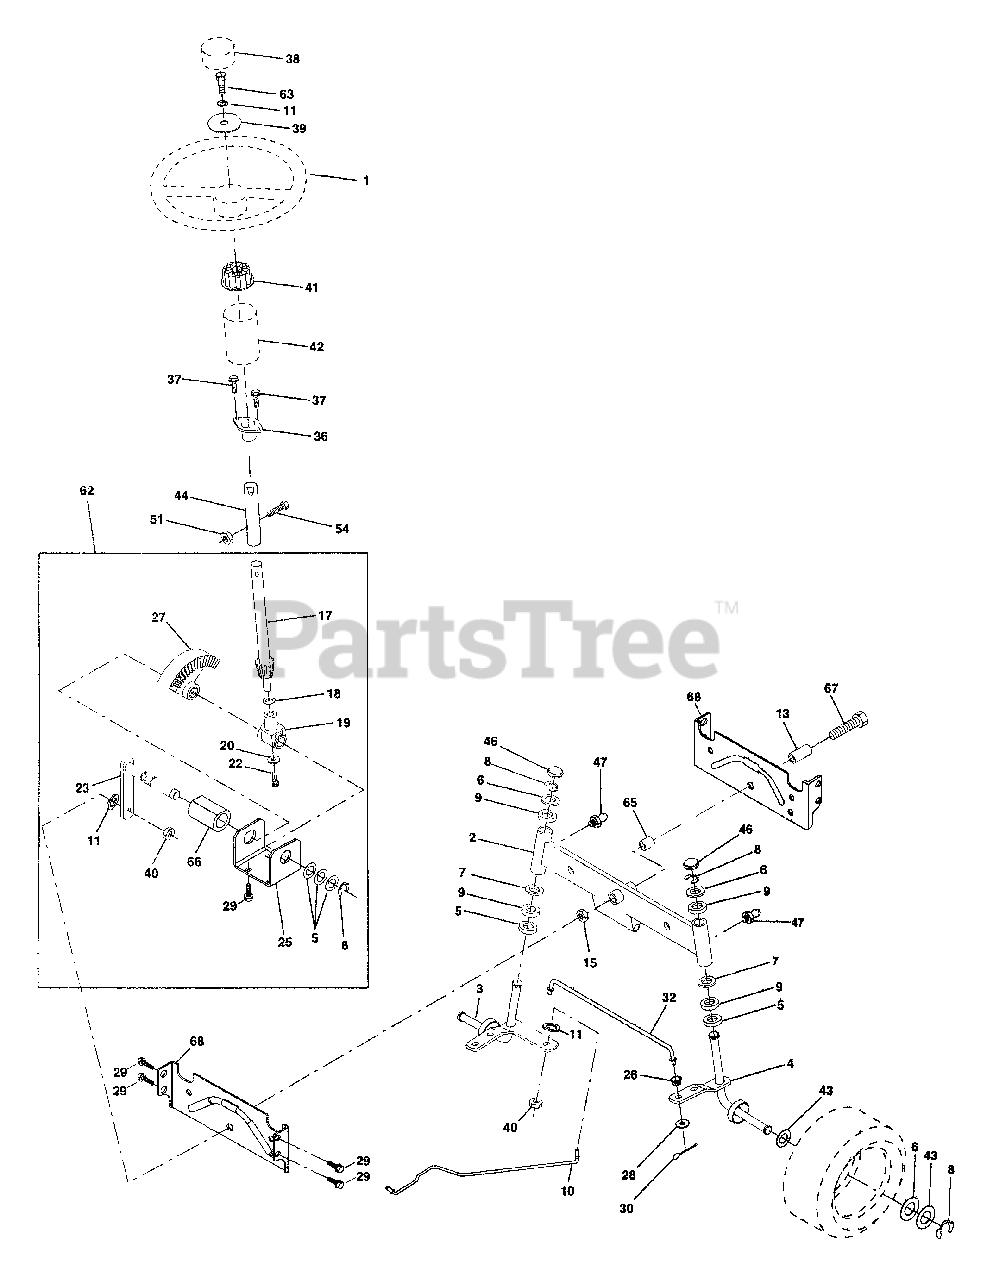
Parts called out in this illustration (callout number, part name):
1	Wheel Steering
2	Axle Asm STMP Dropped STL
3	Spindle Asm LH
4	Spindle Asm RH
5	Bearing Race Thrust Harden
6	Washer 25/32 X 1-5/8 X 16 Ga
7	Washer 27/32 X 1-1/4 X 16 Ga
8	Ring Klip #t5304-75
9	Bearing Col Strg Blk
10	Link Drag Extended Stamp
11	Washer Lock Hvy Hlcl Spr 3/8
13	Bearing Axle STLT/GT
15	Nut Lock Flange 5/8-11 Unc
17	Shaft Asm Strg
18	Washer Thrust 515x 750x 033
19	Support Shaft
20	Washer Shim 1/4 X 5/8 X 062
22	Screw Hex Socket 1/4-20 x 5/8
23	Shaft Asm Pittman
25	Bracket Steering
26	Bushing Link Drag Blk LR
27	Gear Sector
28	Washer 13/32 X 7/8 X 16 Ga
29	Screw Thdrol 3/8-16x3/4 Ty-tt
30	Pin Cotter 1/8 X 3/4 Cad
32	Rod Tie Wire Form 19 75 Mech
36	Bushing Strg
38	Insert Cap Strg Wh Au
39	Washer 13/32 X 2-3/8 X 8 Ga
40	Lock nut
41	Adaptor Wheel Strg
42	Boot Steering Shaft
43	Washer 25/32 X 1 1/4 X 16 Ga
44	Extension Steering Shaft LR/LT
46	Cap Spindle Fr Top Blk
47	Fitting Grease
51	Nut Lock Hex w/Ins 5/16-18
54	Bolt Fin Hex 5/16-18 Unc x 1-1/4
62	Kit, Steering Assembly Svc
63	Bolt Fin Hex 3/8-16unc x 1 Gr. 5
65	Spacer Axle
66	Bearing Arm Pittman
67	Bolt, Fin Hex 5/8-11 UNC x 2-3/4
68	Axle, Brace
